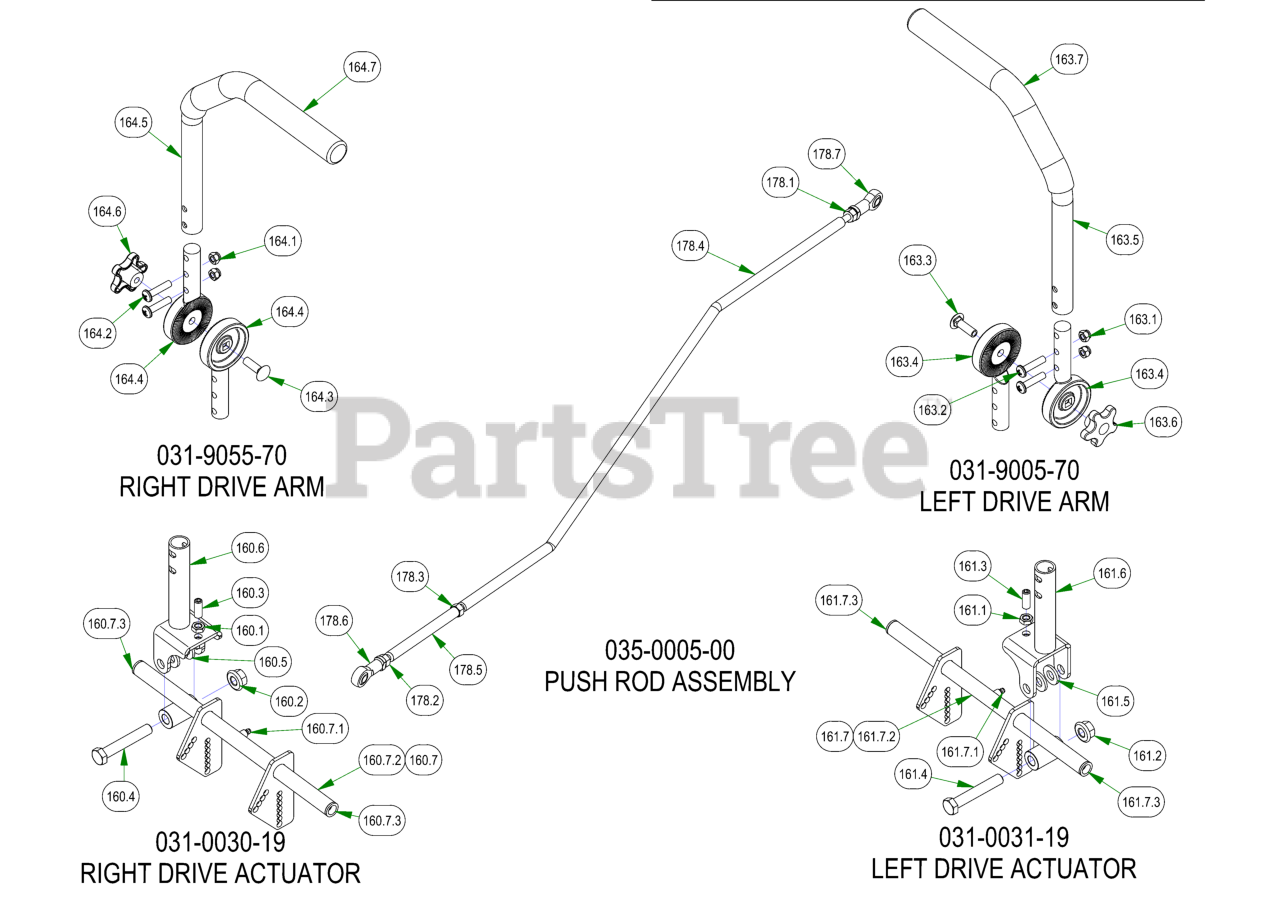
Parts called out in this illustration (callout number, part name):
160	2019 R Series RH Arm Rod Assembly
160.1	3/8-16 Half Jam Nut
160.2	1/2-13 NYLON INSERT FLANGE LOCKNUT ZINC
160.3	3/8-16 X 1 SOCKET SET SCREW (CUP POINT) PLAIN
160.4	1/2-13 X 3 HEX CAP SCREW (GR.5) ZINC
160.5	.505 ID X 1.000 OD X .125 THICK FLAT WASHER NYLON
160.6	Drive Arm Pivot
160.7	2019 Drive Arm Actuator right
160.7.1	1/4" Press in Grease Fitting
160.7.2	2019 Drive Arm Actuator right - Weldment
160.7.3	2019 Drive Arm Bushing
161	2019 R Series LH Arm Rod Assembly
161.1	3/8-16 Half Jam Nut
161.2	1/2-13 NYLON INSERT FLANGE LOCKNUT ZINC
161.3	3/8-16 X 1 SOCKET SET SCREW (CUP POINT) PLAIN
161.4	1/2-13 X 3 HEX CAP SCREW (GR.5) ZINC
161.5	.505 ID X 1.000 OD X .125 THICK FLAT WASHER NYLON
161.6	Drive Arm Pivot
161.7	2019 Drive Arm Actuator left
161.7.1	1/4" Press in Grease Fitting
161.7.2	2019 Drive Arm Actuator left - Weldment
161.7.3	2019 Drive Arm Bushing
163	2019 Left Hand ADJ. Steering Arm Kit
163.1	5/16-18 NYL INS L/N ZC
163.2	5/16-18 x 1 3/8" Futton Head Torx Drive Bolt
163.3	3/8-16 X 1-1/4 CARRIAGE BOLT ZINC
163.4	2019 Steering Arm Adjuster Casting
163.5	2019 Steering Arm Tube
163.6	Black Knob for Adjustable Steering Arm
163.7	Black Steering Arm Grip
164	2019 Right Hand ADJ. Steering Arm Kit
164.1	5/16-18 NYL INS L/N ZC
164.2	5/16-18 x 1 3/8" Futton Head Torx Drive Bolt
164.3	3/8-16 X 1-1/4 CARRIAGE BOLT ZINC
164.4	2019 Steering Arm Adjuster Casting
164.5	2019 Steering Arm Tube
164.6	Black Knob for Adjustable Steering Arm
164.7	Black Steering Arm Grip
178	2019 Renegade Push Rod Assembly
178.1	5/16" RH Fine Threaded Jam Nut
178.2	5/16" LH Fine Threaded Jam Nut
178.3	3/8" Fine Threaded Jam Nut
178.4	2019 Renegade Push Rod
178.5	2019 Renegade Push Rod Adjuster
178.6	Spherical Rod End - Outlaw
178.7	Spherical Rod End - Outlaw
